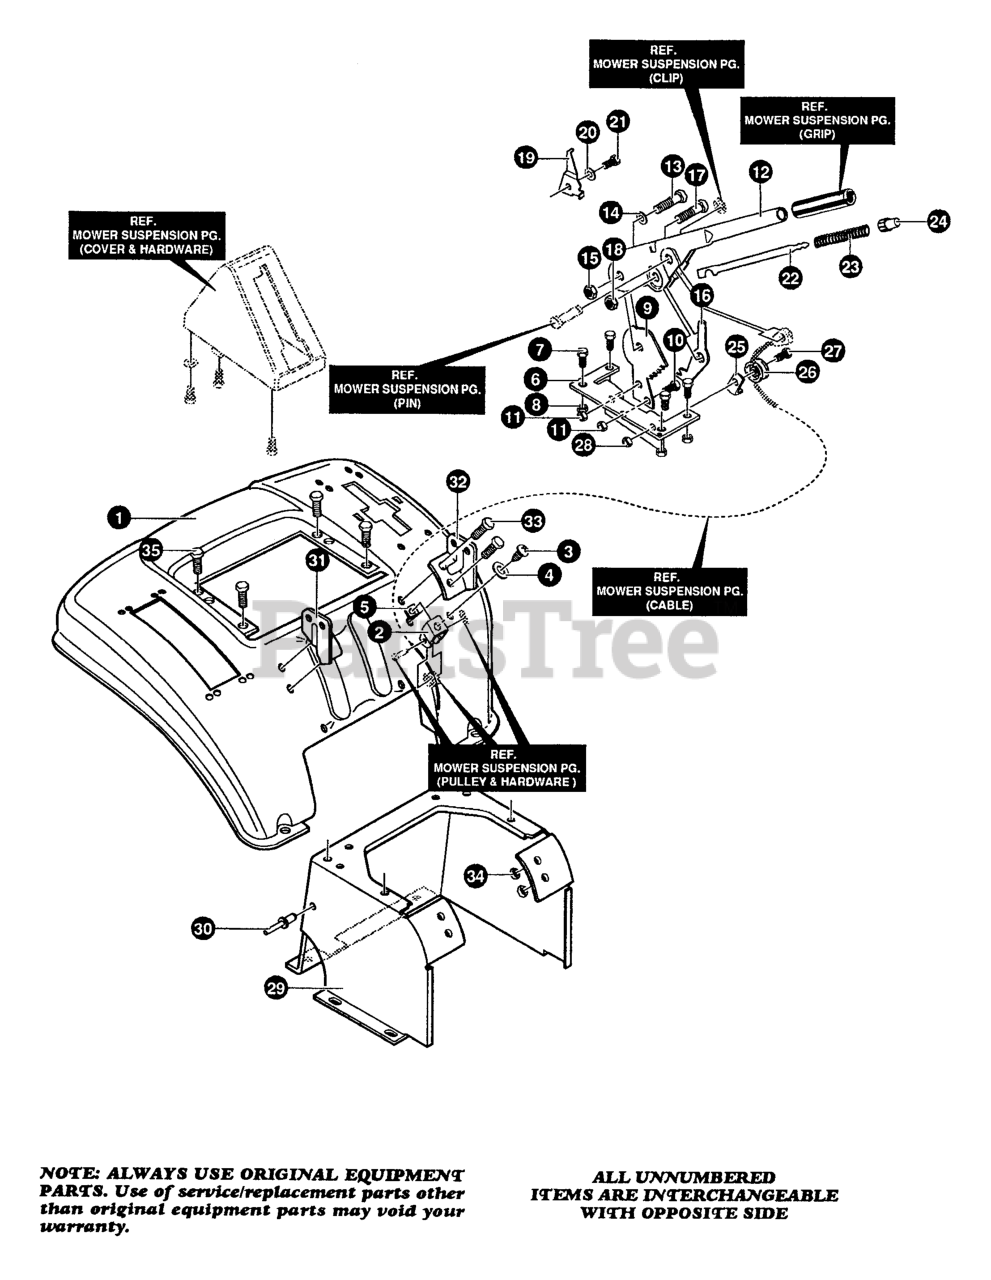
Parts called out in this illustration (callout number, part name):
1	FENDER, WALK-THRU
2	CLEVIS
3	SCREW, 5/16-18 x 0.56
4	WASHER, .344ID x 1.50D x .09
5	NUT, 5/16-18 SQ
6	BRACKET, HEIGHT ADJUST
7	SCREW, 5/16-18 x 0.75
8	NUT, 5/16-18
9	QUADRANT, HEIGHT ADJUST
10	SCREW, 5/16-18 x 0.75
11	NUT, 5/16-18
12	HANDLE, LIFT SHORT
13	BOLT, .500 X .270
14	WASHER, FLAT .506 x .75 x .024
15	NUT, 5/16-18
16	PAWL, SQUARE
17	BOLT, .500 x .270
18	NUT, 5/16-18
19	POINTER
20	WASHER, .195 x .41 x .03
21	SCREW, #8-32 x .38
22	ROD, ACTUATOR-SHORT
23	SPRING, HEIGHT ADJUST
24	KNOB, HEIGHT ADJUST PUSH BUTTON
25	CABLE RETAINING BRACKET
26	PULLEY, METAL
27	BOLT, .375 x .375
28	NUT, 1/4-20
29	SEAT/FENDER SUPPORT
30	RIVET, POP
31	BRACKET SEAT, RH
32	BRACKET SEAT, LH
33	SCREW, 5/16-18 x 0.63
34	NUT, 5/16-18
35	SCREW, 1/4-20 x .50
